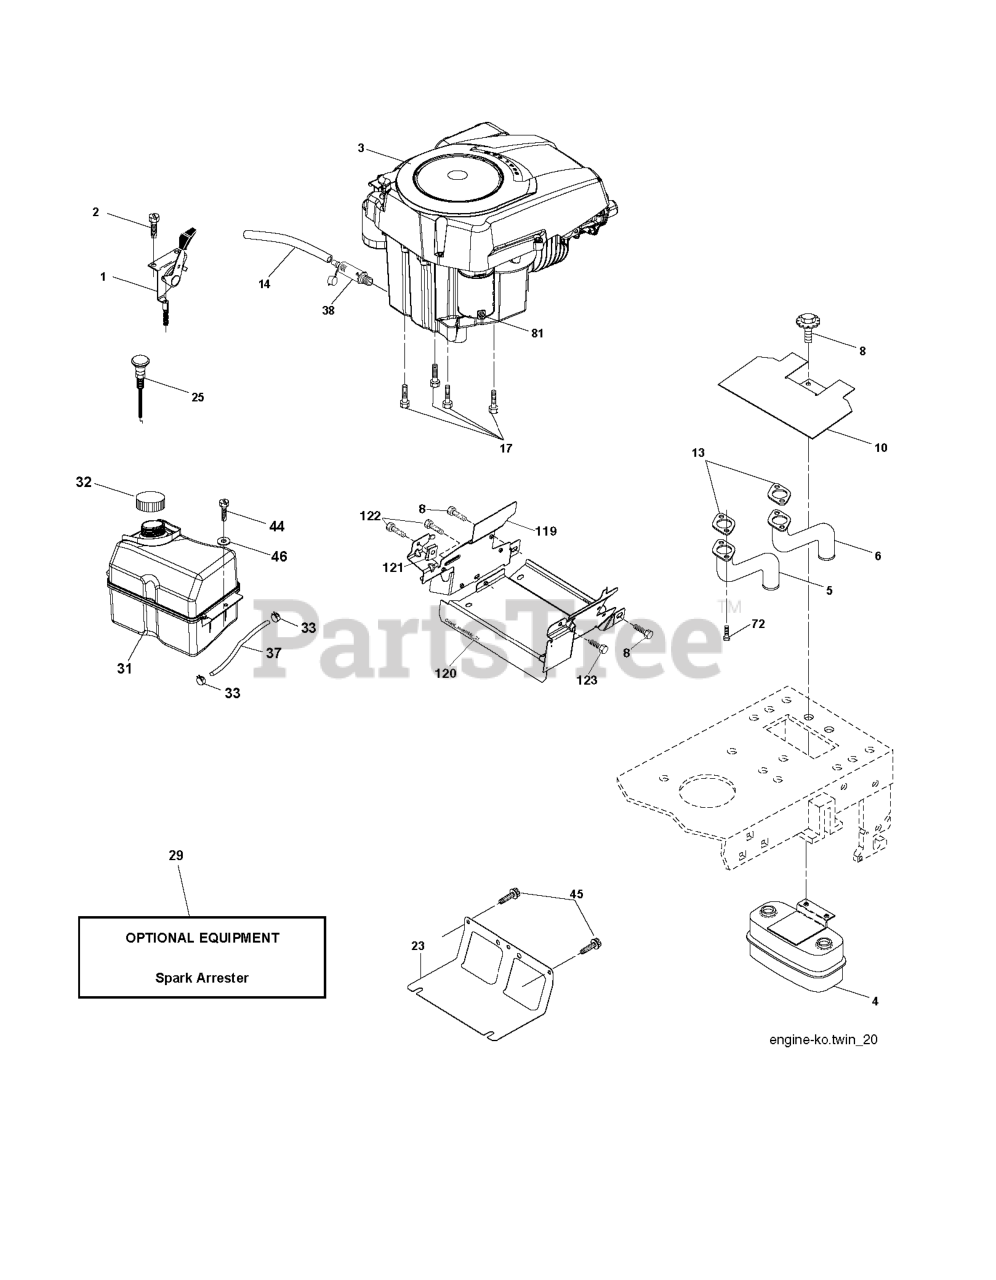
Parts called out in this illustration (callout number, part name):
1	THROTTLE CONTROL
2	SCREW
4	MUFFLER.TWIN.CYL.LOW.TONE
5	RP.PIPE-EXHAUST LH
6	RP.PIPE-EXHAUST RH
8	BOLT.5/16-18UNCX3/4 W/SEMS.BLK
10	RP SHIELD HEAT MUFFLER
14	TUBE, DRAIN OIL ASM.
17	SCREW 3/8-16X1
23	SHIELD.BROWNING.DBR.GUARD
25	CONTROL, CHOKE
29	KIT.SPARK ARRESTOR 794945 B&S
31	TANK.ASM.FUEL.FR.2.5GA.
32	FUEL CAP
33	HOSE CLAMP
37	LINE.FUEL.20
38	PLUG DRAIN OIL EASY
44	SCREW HEXWSHR 1/4-20X3/4
45	SCREW, 3/8-16X3/4
72	SCREW.SOCKET HD.5/16-1
81	NUT
119	LENKRAD
120	GUARD 532199767
122	SCREW.1/4-20X5/8
123	SCREW, 5/16-18 X 1/2
